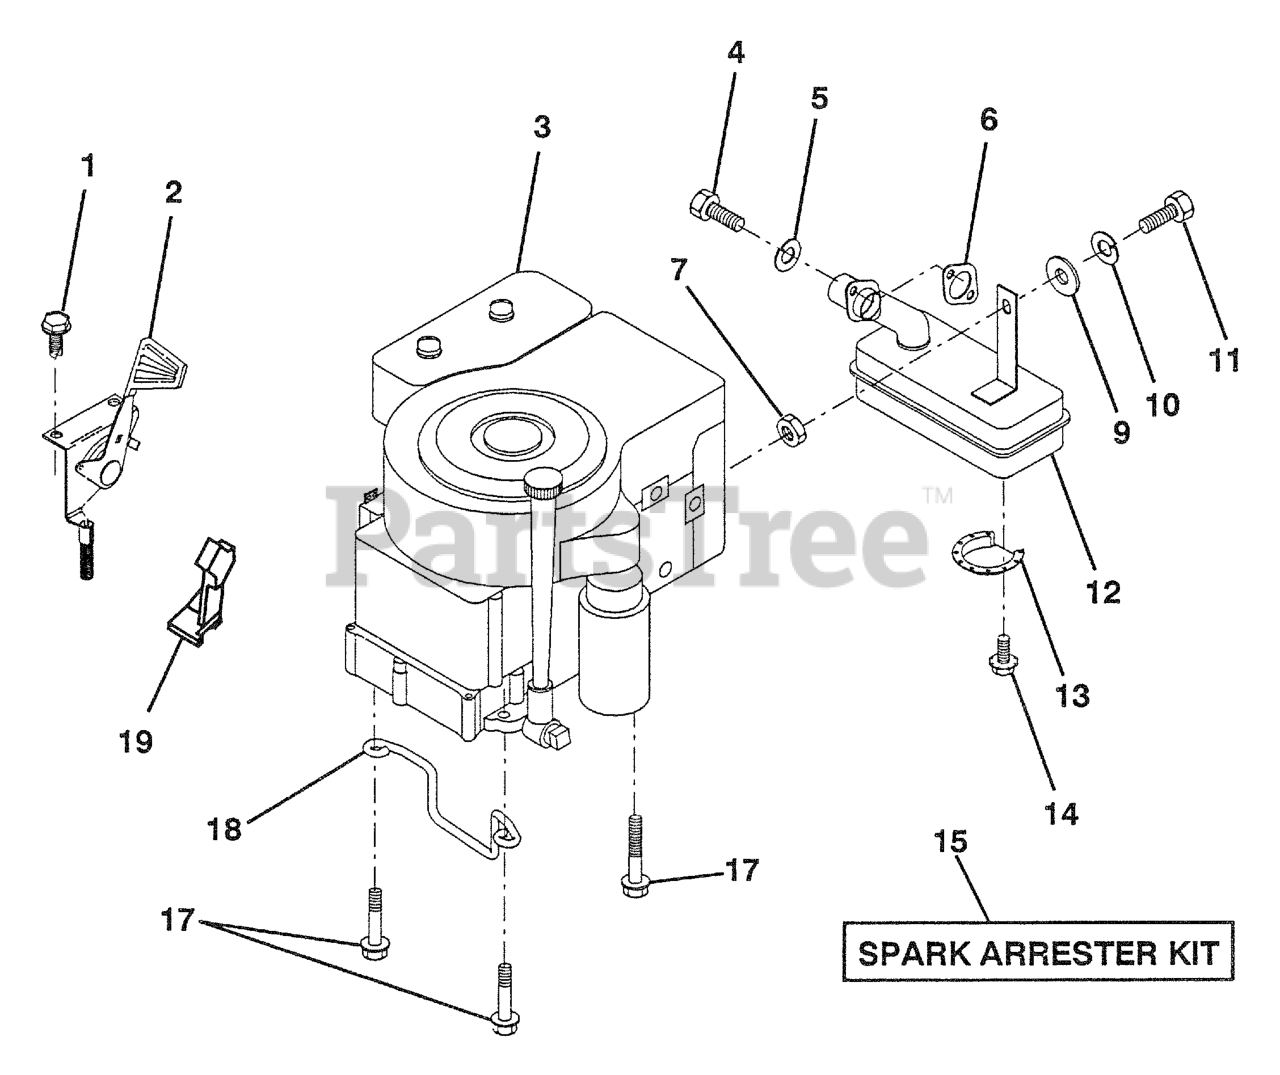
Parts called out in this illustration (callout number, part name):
1	SCREW
2	CONTROL.TH/CH.RH.BLK.FLG.EEC
4	SCREW
5	WASHER.LOCK.HVY.HLCL.SPR.5/16
6	GASKET ENGINE
7	NUT
9	WASHER
10	LOCKWASHER
11	BOLT
12	MUFFLER
13	DEFL MUFFLER LTV
14	SCREW
15	SPARK ARREST
17	SCREW LT
18	KEEPER,DR BELT GR
19	STOP THROTTLE
